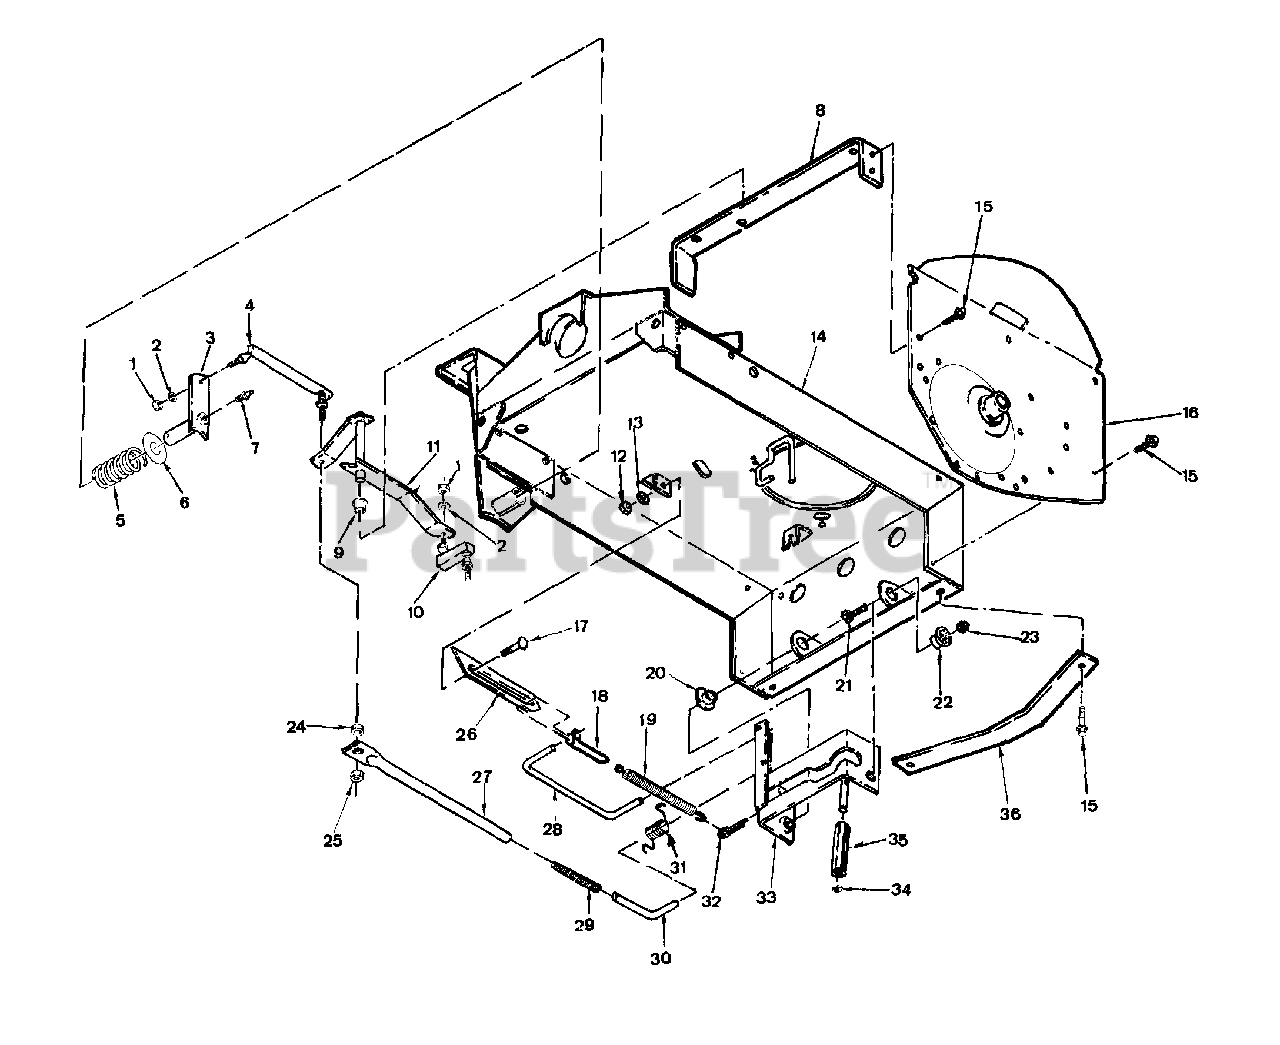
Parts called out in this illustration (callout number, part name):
1	NUT, 5/16-24 Hex
2	5/16 Lock Washer
3	Shift Handle Arm
4	Shift Link, Long
5	Spring
6	Thrust Washer
7	FITTING, Lube (Press fit for .187 hole-no ball)
8	Cross Brace
9	Nylon Bushing
10	Shift Link, Short
11	Shift Arm
12	3/8-16 Hex Nut
13	3/8 Lock Washer
14	Main Case
15	5/16-18 x 5/8 HW ST Screw
16	Fender, Left Hand
17	3/8-16 x 3/4 Carriage Bolt
18	Clutch Clevis
19	Spring
20	Thrust Washer
21	5/16-18 x 1 ST Screw
22	Yoke Bearing, Right Hand
23	5/16-18 Hex Nut
24	Roller
25	5/16-24 Hex Lock Nut
26	Rod Guide
28	Clutch Rod
29	Spring
30	Rod
31	Spring
32	3/16 x 3/4 Cotter Pin
33	LIFT, Yoke
34	Retaining Ring
36	Hitch Plate
